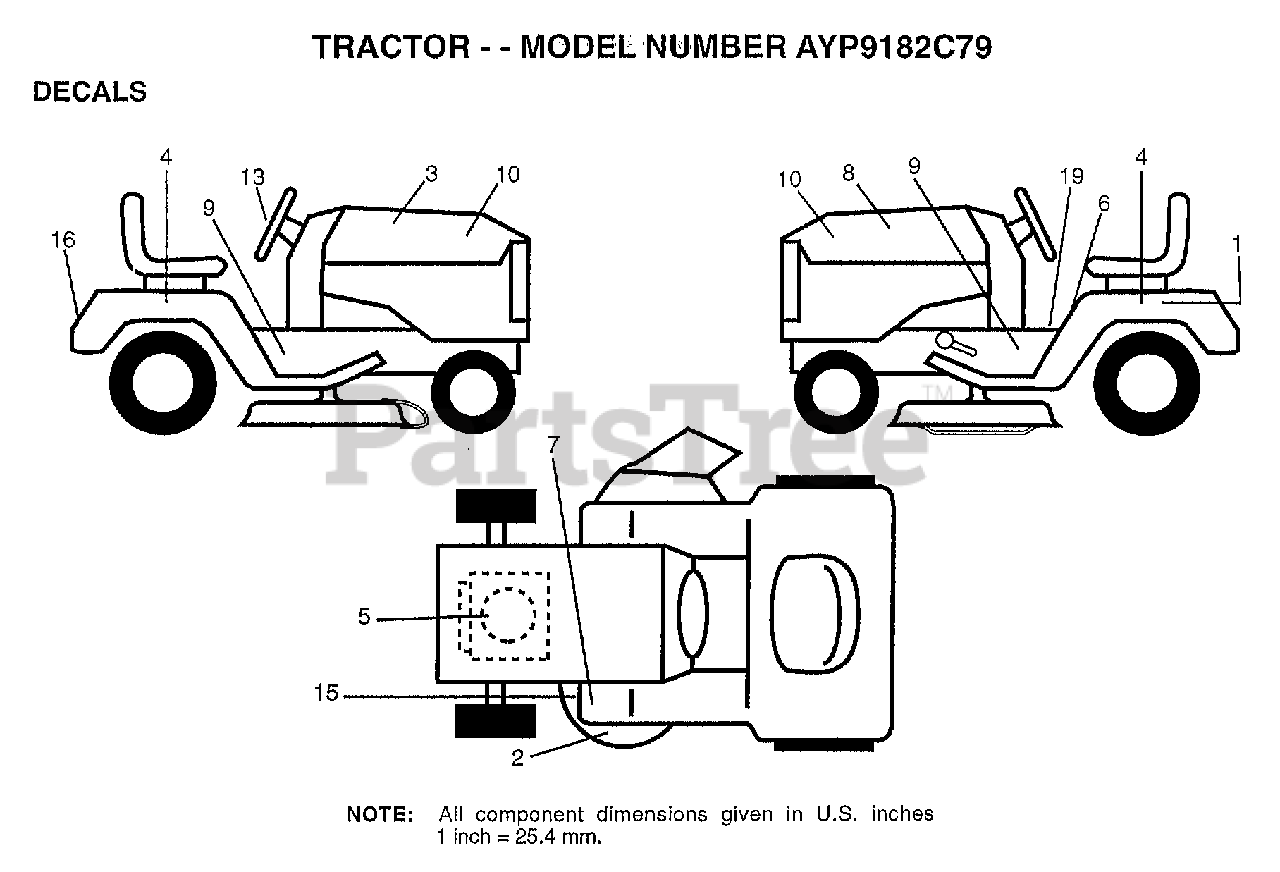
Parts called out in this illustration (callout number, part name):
1	DECAL.BATRY.3-3908
2	DECAL DECK WIZ +
3	DECAL.HD.RH.WIZAR
4	DECAL.FENDER.WIZ
5	DECAL, HP, ENGINE
6	"DECAL DANGER,FEND"
8	DECAL.HD.LH.WIZAR
9	"DECAL.CHASSIS.42"""
10	DECAL INSERT HOOD
13	DECAL.INS.STRG.WL
15	DECAL
19	"DECAL INST,SADDLE"
